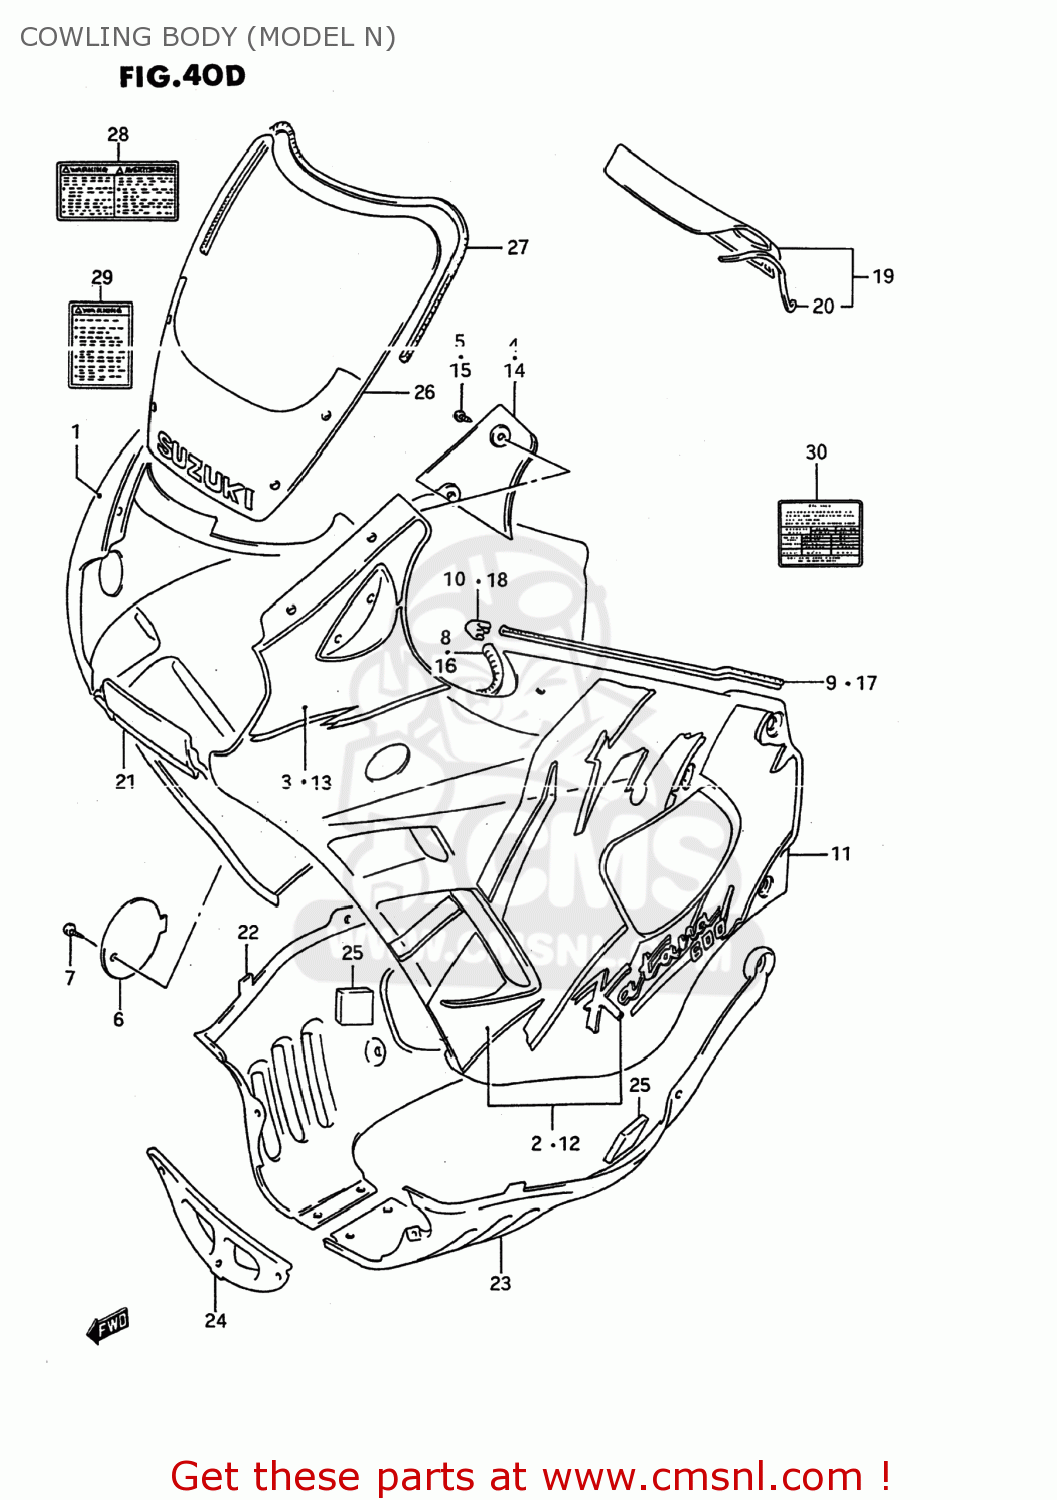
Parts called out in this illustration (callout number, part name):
1	COVER ASSEMBLY,COWLING,RIGHT
2	TAPE SET,BODY COWLING SIDE
3	TAPE,BODY COWLING SIDE,UPPER
4	COVER,COWLING METER SIDE,R
5	SCREW
6	LID,OIL
7	SCREW(6X16)
8	MOLDING
9	MOLDING
10	JOINT,MOLDING END
11	COVER ASSEMBLY,COWLING,LEFT
12	TAPE SET,BODY COWLING SIDE
13	TAPE,BODY COWLING SIDE,UPPER
14	COVER,COWLING METER SIDE,L
15	SCREW
16	MOLDING
17	MOLDING
18	JOINT,MOLDING END
19	COVER,METER
20	MOLDING
21	PANEL,COWLING CTR
22	COVER,COWLING UNDER,R
23	COVER,COWLING UNDER,L
24	COVER,COWLING UNDER FR
25	CUSHION,UNDER COWLING
26	WINDOW COMP,COWLING
27	MOLDING
28	LABEL,GENERAL WARNING
29	LABEL (WARNING SCREEN)
30	LABEL (TIRE INFORMATION)
